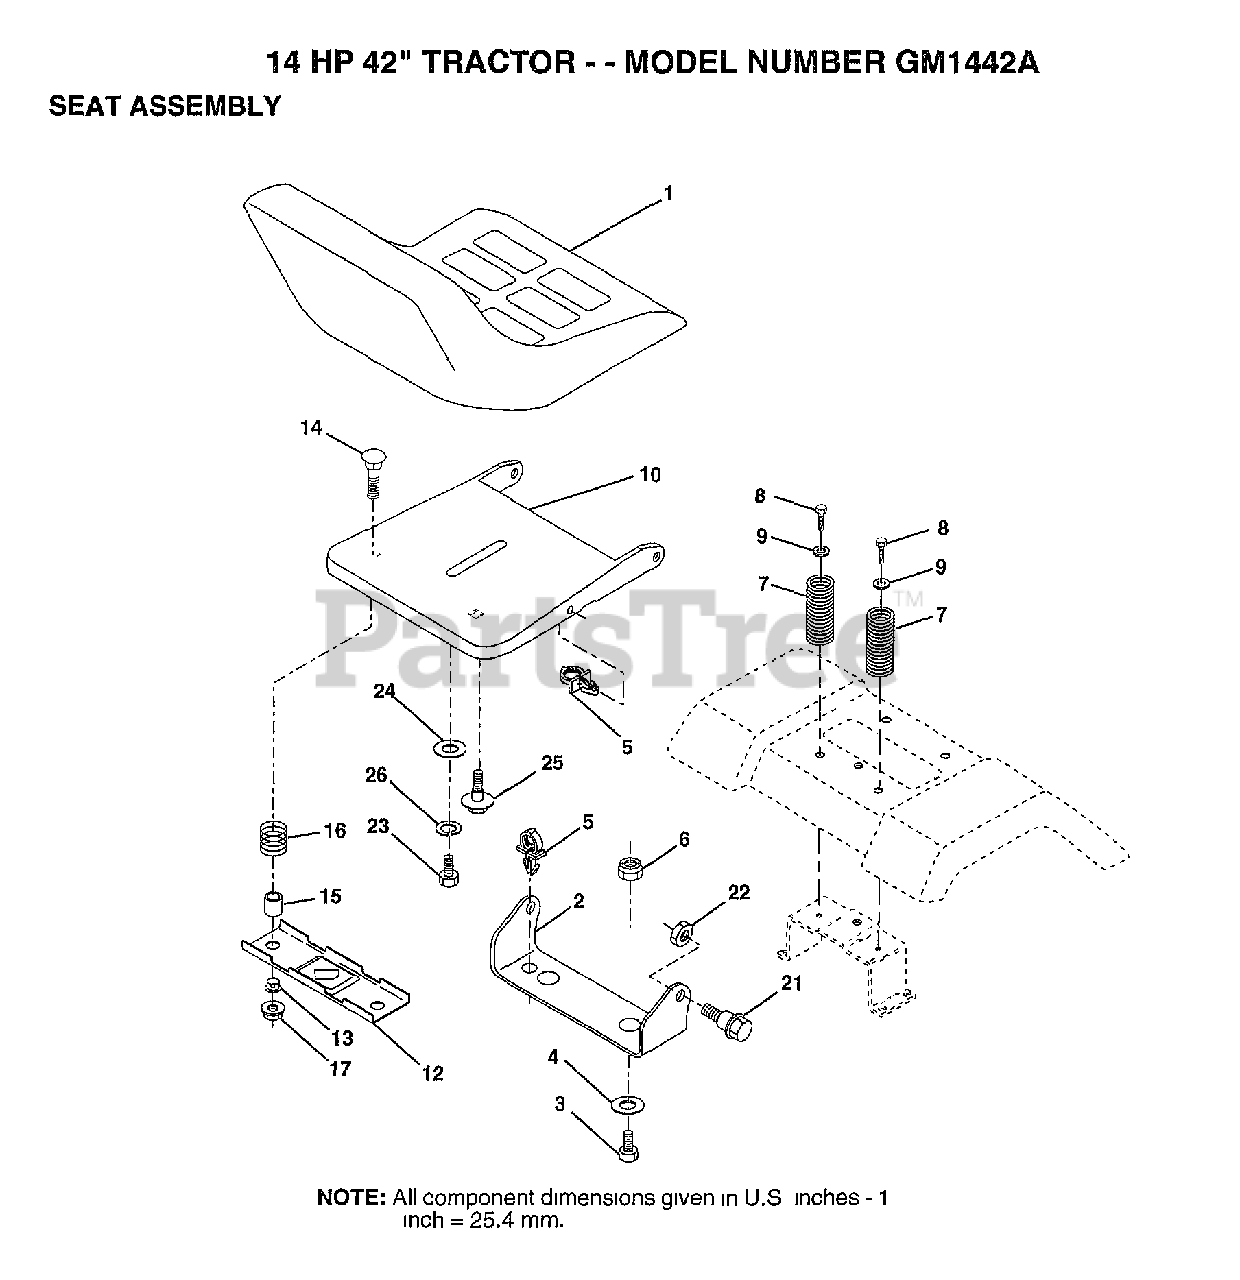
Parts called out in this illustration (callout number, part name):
2	BRACKET PVT SEAT
3	BOLT
4	WASHER PM
5	CLIP PUSH - IN
6	NUT
7	SPRING COMPRESSIO
8	SCREW GTV
9	WASHER
12	BRKT SWITCH
13	BUSHING
15	SPLIT SPACER
16	SPRING
21	BOLT.SHLD.5/16-18
22	NUT
23	BOLT
24	WASHER
25	"BOLT,SHOULDER"
26	LOCKWASHER
